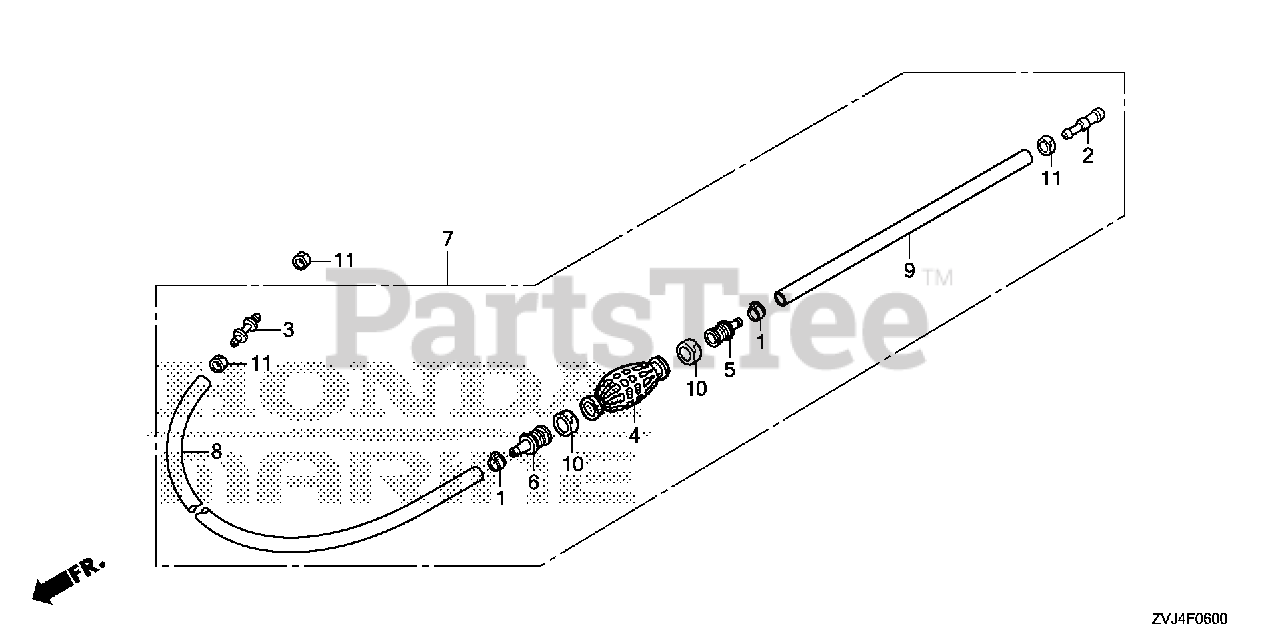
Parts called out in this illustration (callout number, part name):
1	CLAMP, FUEL TUBE (14.0) (CONNECTOR TYPE)
2	JOINT, FUEL TUBE (JOINT TYPE)
3	JOINT, FUEL TUBE
4	BULB, PRIMER
5	VALVE, IN.
6	VALVE, OUTLET
7	TUBE, FUEL TANK
8	TUBE, FUEL LONG (75)
10	BAND, TUBE CLIP (20MM)
11	BAND, TUBE CLIP (12.5MM)
